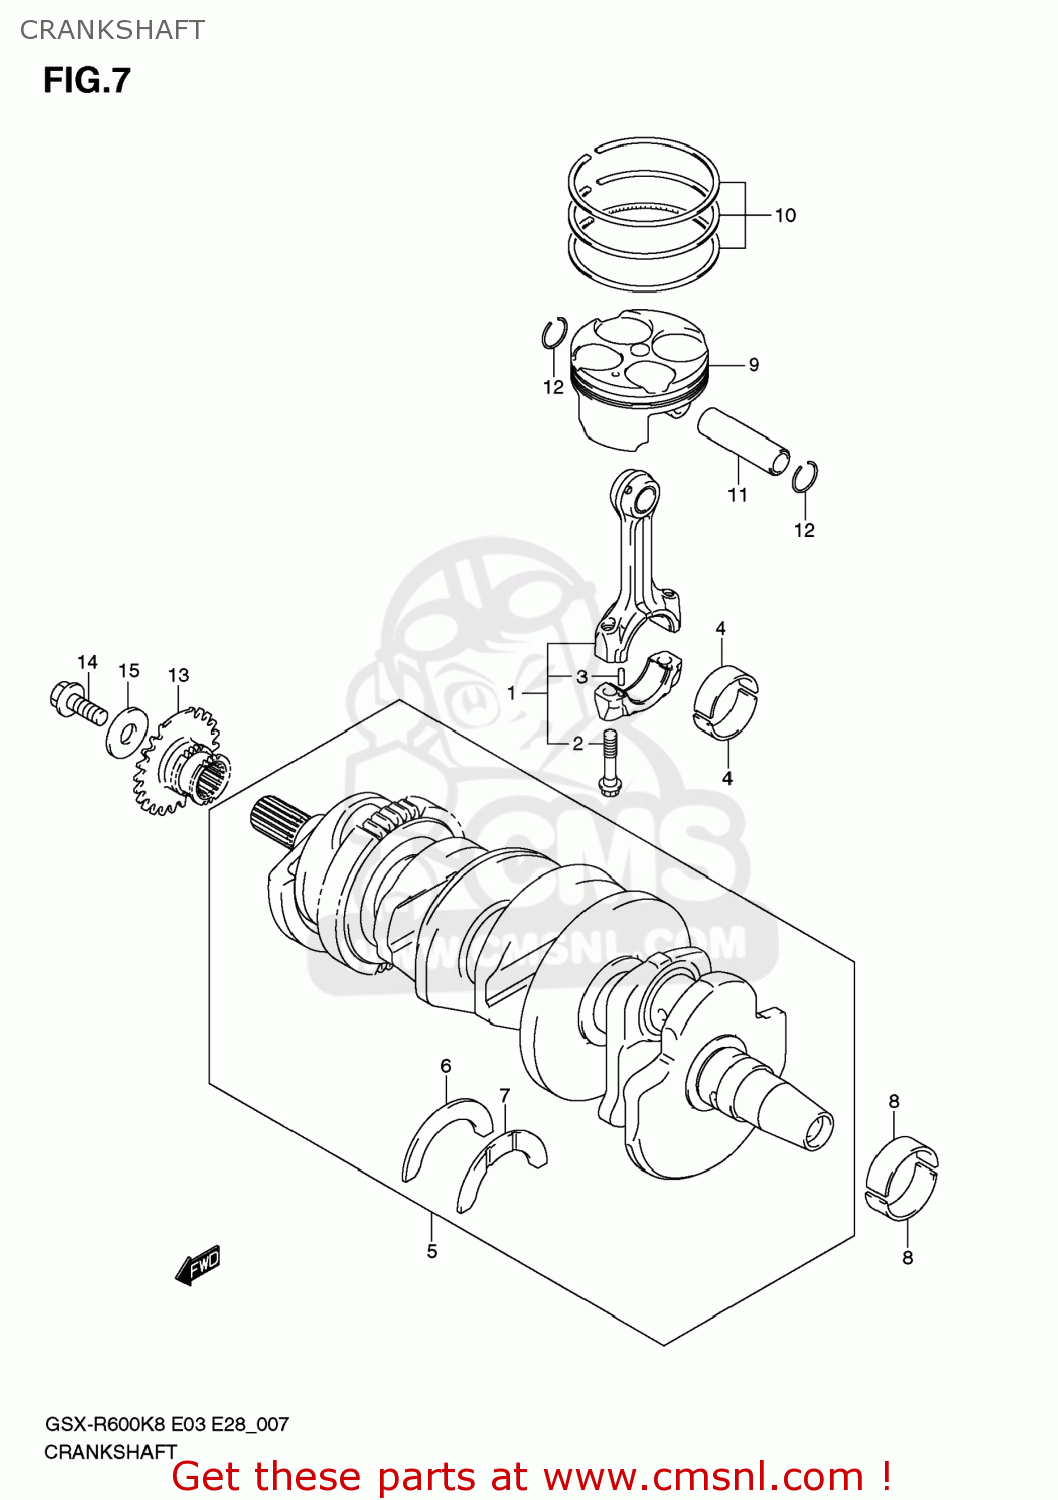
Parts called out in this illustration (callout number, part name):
1	CONNECTING ROD ASSY
2	BOLT,CONNECTING ROD
3	PIN
4	BEARING,CRANK PIN
5	CRANKSHAFT SET
6	BEARING,CRANK THRUST(GREEN)
7	BEARING,CRANK THRUST(RED)
8	BEARING,CRANKSHAFT
9	PISTON
10	RING SET,PISTON
11	PIN,PISTON
12	RING,SNAP 14MM
13	SPROCKET,CAM CHAIN DRIVE
14	BOLT(10X23)
15	WASHER
